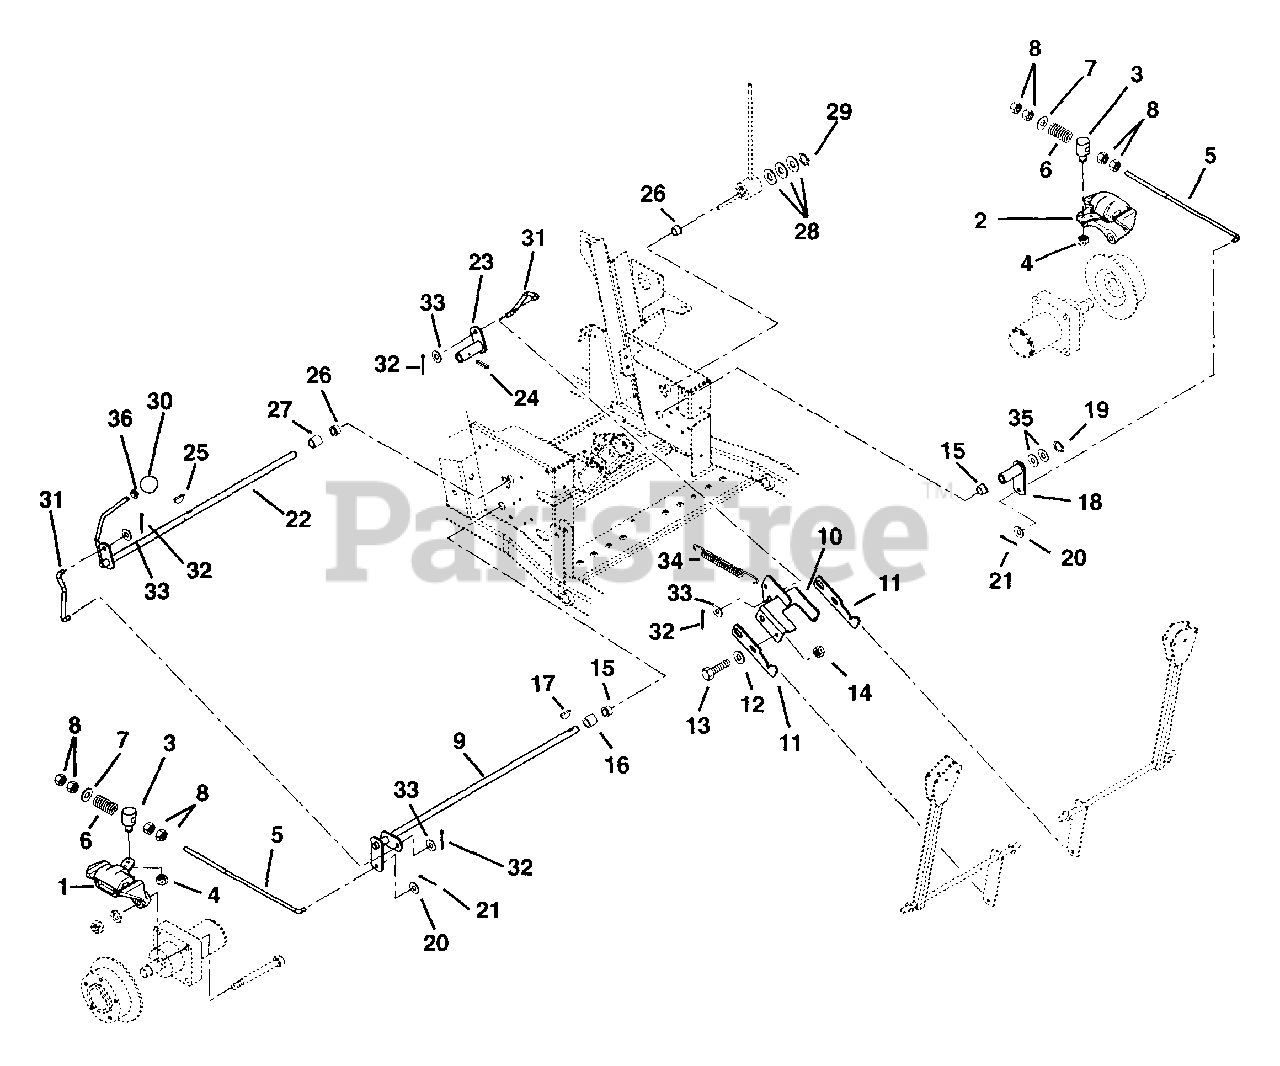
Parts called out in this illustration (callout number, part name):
1	Caliper, Park Brake (CW) Right Hand
2	Caliper, Park Brake (CCW) Left Hand
3	Pivot-Brake Rod
4	Nut-Locking-Center .31-18
5	Rod-Brake
6	Spring-Compression .143 x .710 x 2.00
7	Washer-Flat-Steel .406 x .812 x .065
8	Nut-Hex .38-16
9	Shaft-Brake Cross
10	Interlock-Fixed
11	Interlock-Adjustable
12	Washer-Flat-Steel .406 x .812 x .065
13	Bolt-Hex .38-16 x 1.00 Grade 5
14	Nut-Locking-Center .38-16
15	Bushing-Flange .630 x 1.000 x .625
16	Spacer .630 x .878 x 1.000
17	Key-Woodruff .19 x .75 Hard #9
18	Arm-Brake Left-Hand
19	Ring-Retaining-External .625 x .050
20	Washer-Flat-Steel .406 x .812 x .065
21	Pin-Cotter External .09 x .75
22	Shaft-Brake Actuating
23	Actuator
24	Pin-Roll .125 x 1.00
25	Key-Woodruff .19 x .75 Hard #9
26	Bushing-Flange .630 x 1.000 x .625
27	Spacer .630 x .878 x 1.000
28	Washer-Flat-Steel .627 x .990 x .032
29	Ring-Retaining-External .625 x .050
30	Knob-Steering Lock
31	Rod-Brake Actuating
32	Pin-Cotter-External .09 x .75
33	Washer-Flat-Steel .406 x .812 x .065
34	Spring-Tension .105 x .85 x 5.00
35	Washer-Flat-Steel .656 x 1.31 x .095
36	Nut-Hex-Jam .375-16
